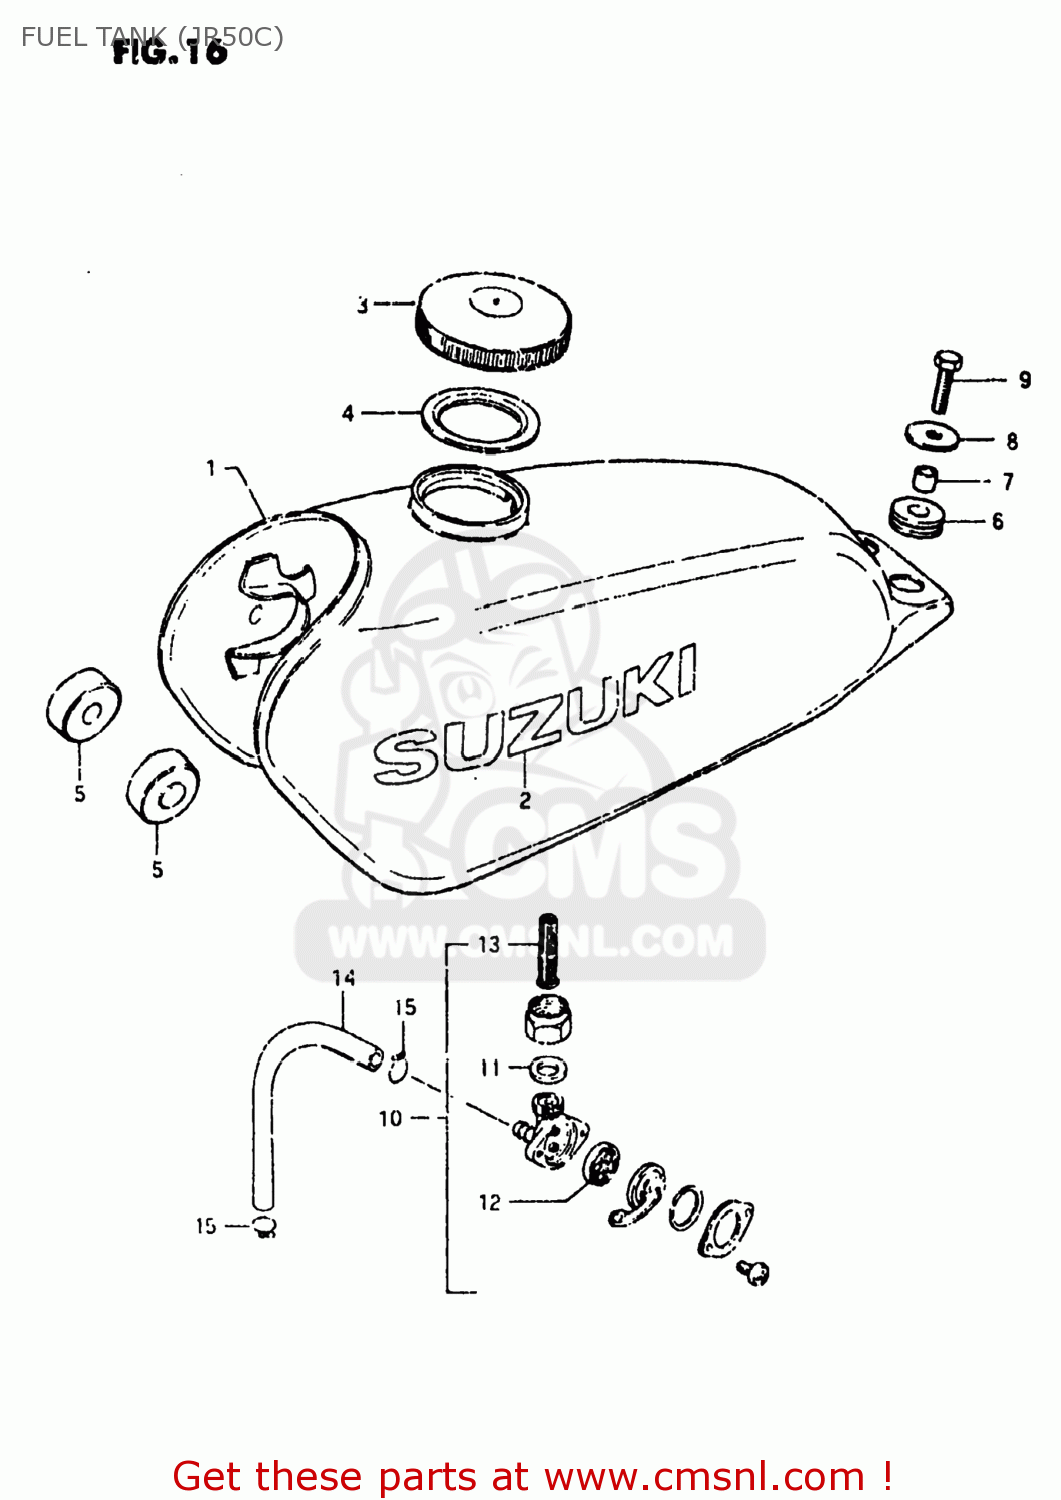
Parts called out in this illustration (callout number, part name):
1	TANK ASSEMBLY,FUEL
2	EMBLEM,REAR FENDER
3	CAP SET,FUEL TANK
4	GASKET,CAP (NAS)
5	CUSHION
6	CUSHION
7	SPACER(6.1X9X7.5)
8	WASHER (6.5X24X1.6)
9	BOLT, UPPER
10	COCK ASSEMBLY,FUEL
11	GASKET,FUEL COCK (NAS)
12	PACKING,VALVE (NAS)
13	FILTER,FUEL
14	HOSE
15	CLIP
